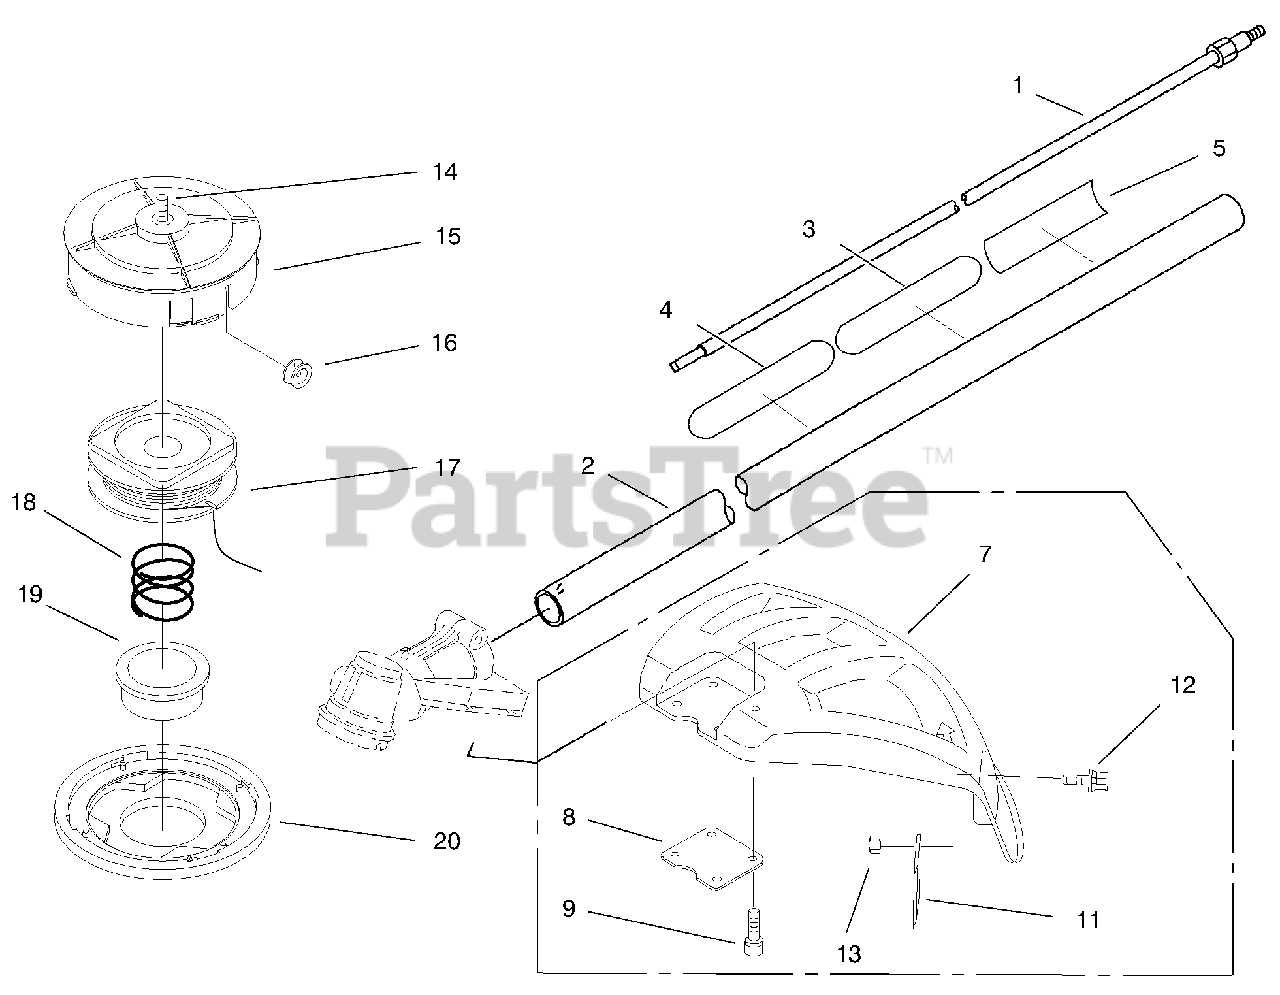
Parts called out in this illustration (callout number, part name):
1	DRIVE SHAFT-STRAIGHT
2	Driveshaft Tube Asm (Incl. Ref. #3,4)
3	DECAL - CAUTION
4	DECAL - CAUTION
5	DECAL - TORO
7	SAFETY COVER
11	STRING CUTTER
17	SPOOL W/LINE (LH)
20	COVER (SN-348L)
